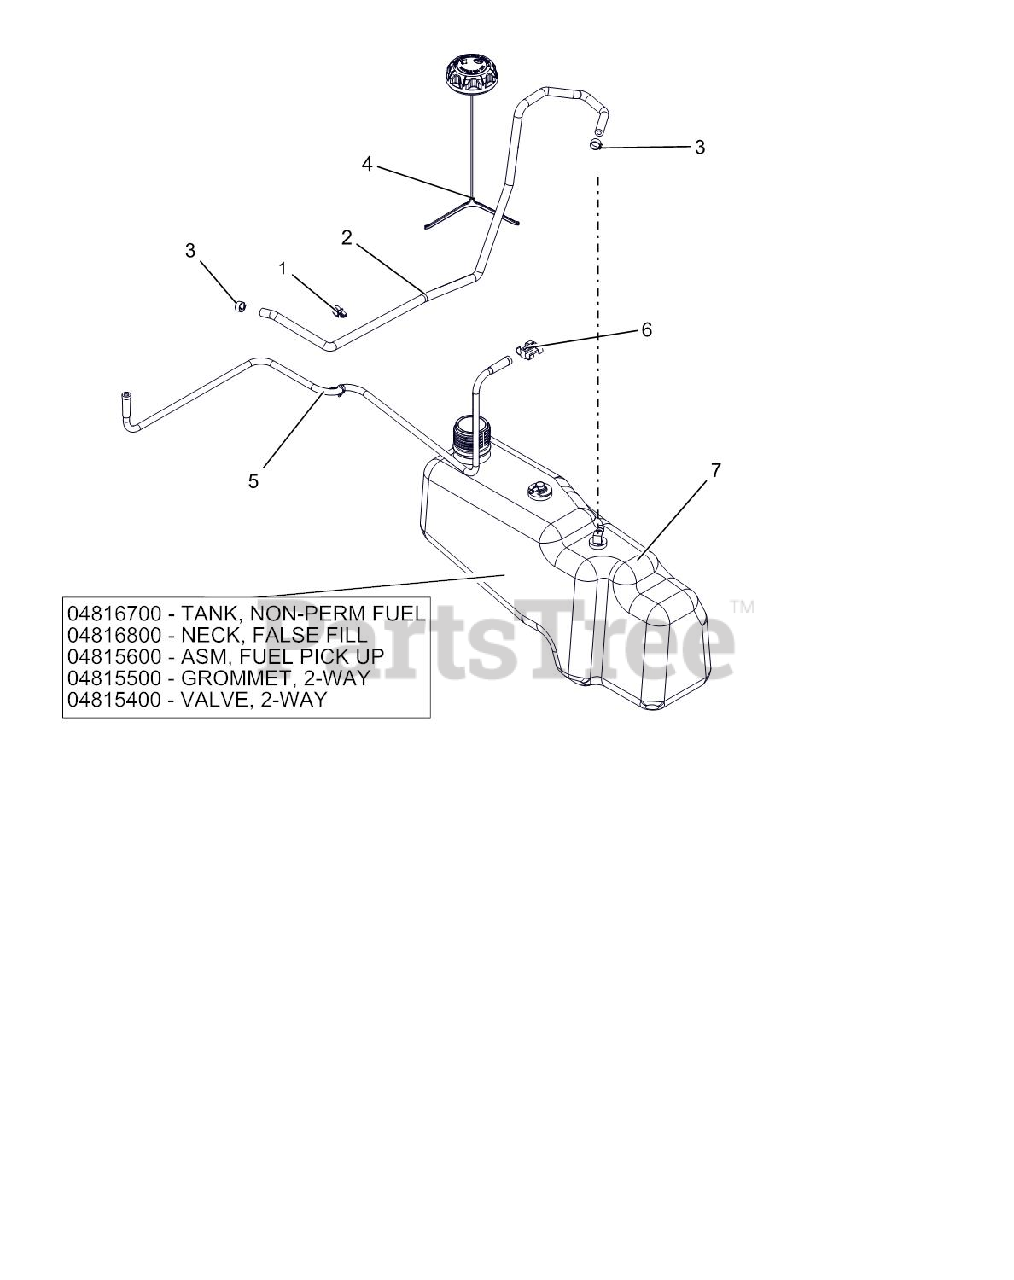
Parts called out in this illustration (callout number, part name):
1	ROUTING CLIP (1/2" ID)
2	HOSE, .25 LOW-PERM BULK GAS
3	CLAMP, FUEL LINE
4	CAP, FUEL VENT-IN 2.25" RATCH.
5	LINE, FUEL VENT KOHLER
6	CLIP, T, .38-.50
7	GROMMET, 2-WAY
7	VALVE, 2-WAY
7	ASM,TANK NON-PERM FUEL
7	NECK, FALSE FILL ZOOM/ZT
7	ASM, FUEL PICK-UP ZOOM/ZT 2015
7	TANK, ZOOM/ZT NON-PERM, FUEL
